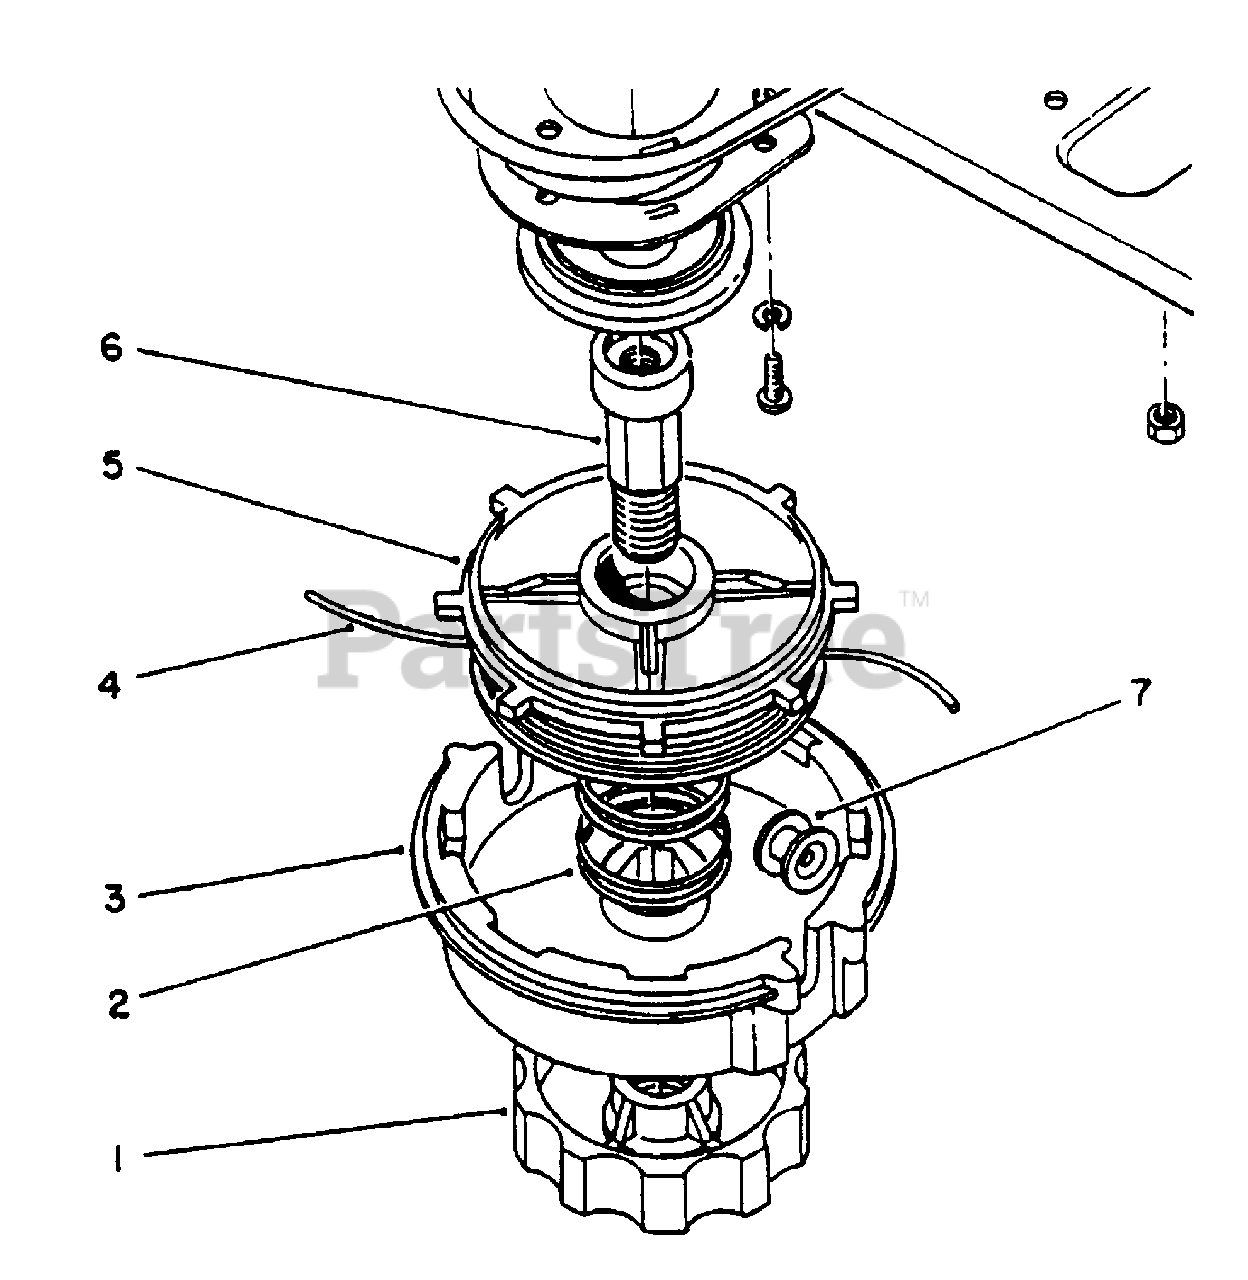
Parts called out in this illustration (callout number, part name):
1	Knob-L.H.
3	Spool-Housing
5	Spool-Inner
